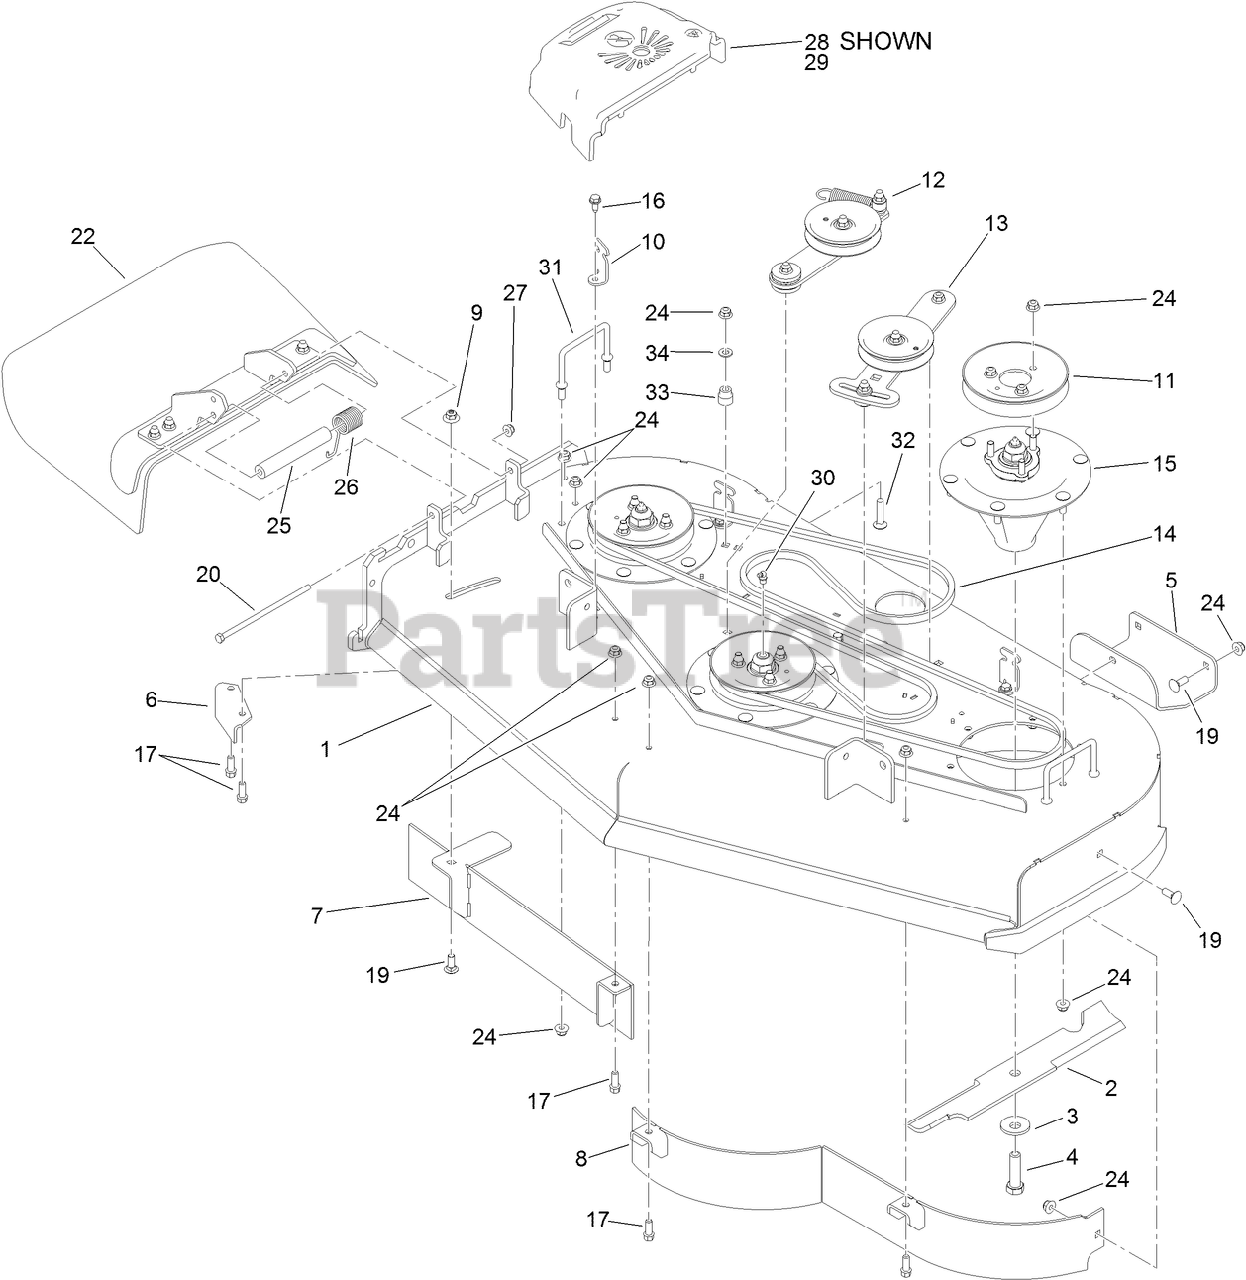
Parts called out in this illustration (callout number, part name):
1	DECK ASM
2	BLADE-16.5 INCH (HIGH FLOW)
3	Washer-Blade Bolt, Heavy
4	SCREW-BLADE
6	BAFFLE-DISCHARGE
8	48 INCH BAFFLE ASM
9	NUT-FLANGE, NI
10	BRACKET-COVER
11	PULLEY
12	IDLER ARM ASM
13	IDLER ADJUST ASM
14	BELT-V
15	SPINDLE ASM
16	SCREW-HWHTF
17	SCREW-HWH
19	BOLT-CARR
20	SCREW-HH
22	DEFLECTOR ASM
24	NUT-HF, NI
25	SPACER
26	SPRING-TORSION
27	NUT-HF, NI
28	COVER-BELT, RH
29	COVER-BELT
30	FITTING-GREASE
31	WIREFORM-COVER
32	SCREW-CARR
33	BUSHING-IDLER
34	WASHER-FLAT
